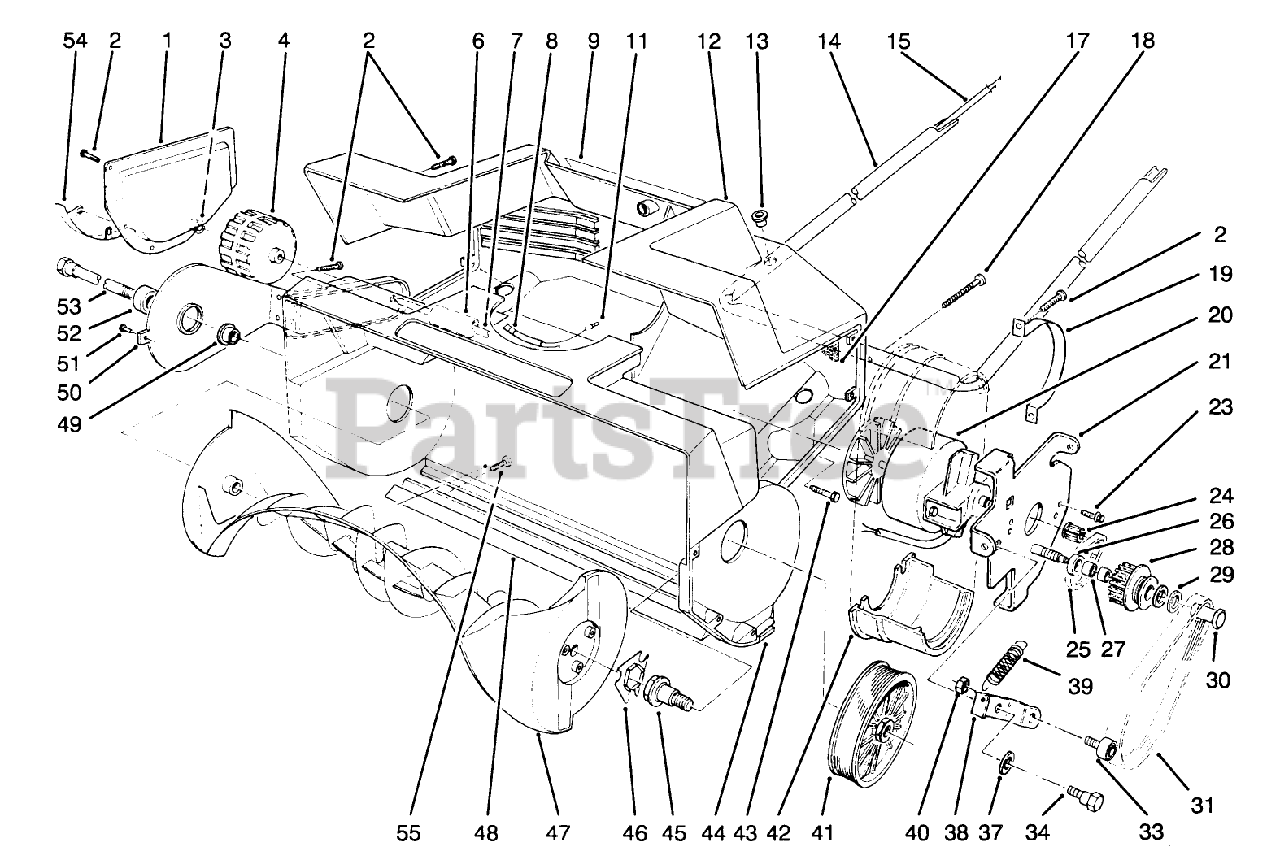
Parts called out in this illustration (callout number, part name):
3	PUSHNUT-CAP, WASHER
4	WHEEL, 1200/1800
7	AXLE SHAFT
8	STRAIN RELIEF-GRIPMASTR
11	CONNECTOR SCREW
12	SHROUD - 1800 P.C.
13	BUSHING
17	FOAM FILTER
18	SCREW-PLASTIC, PPH
19	STRAP-MOTOR, FINISHED
20	MOTOR, 1800
21	PLATE - MOTOR ASSY.
23	TEKS SCREW
24	DRIVER PULLEY
25	BELT-PULLEY, IDLER/DRIVER
26	WASHER
27	DISC - ORD PULLEY
29	WASHER-THRUST
30	IDLER BOLT
33	IDLER BEARING
34	SCREW-SHOULDER
37	WASHER
38	IDLER BRACKET
39	IDLER SPRING
40	NUT-LOCK, NI
41	DRIVEN PULLEY
42	1800 CLAMP MTR BRCKT
43	SCREW-HWH THD CUT
44	ROTOR/HOUSING 1800
45	SHAFT, ROTOR DRIVE
46	COUPLER, ROTOR
47	ROTOR - 1800 SNOWBLOWER
48	SCRAPER - 1800
49	BUSHING
50	WHEEL BRKT ASSY/1800
51	RIVET-POP
54	SKID, 1800
